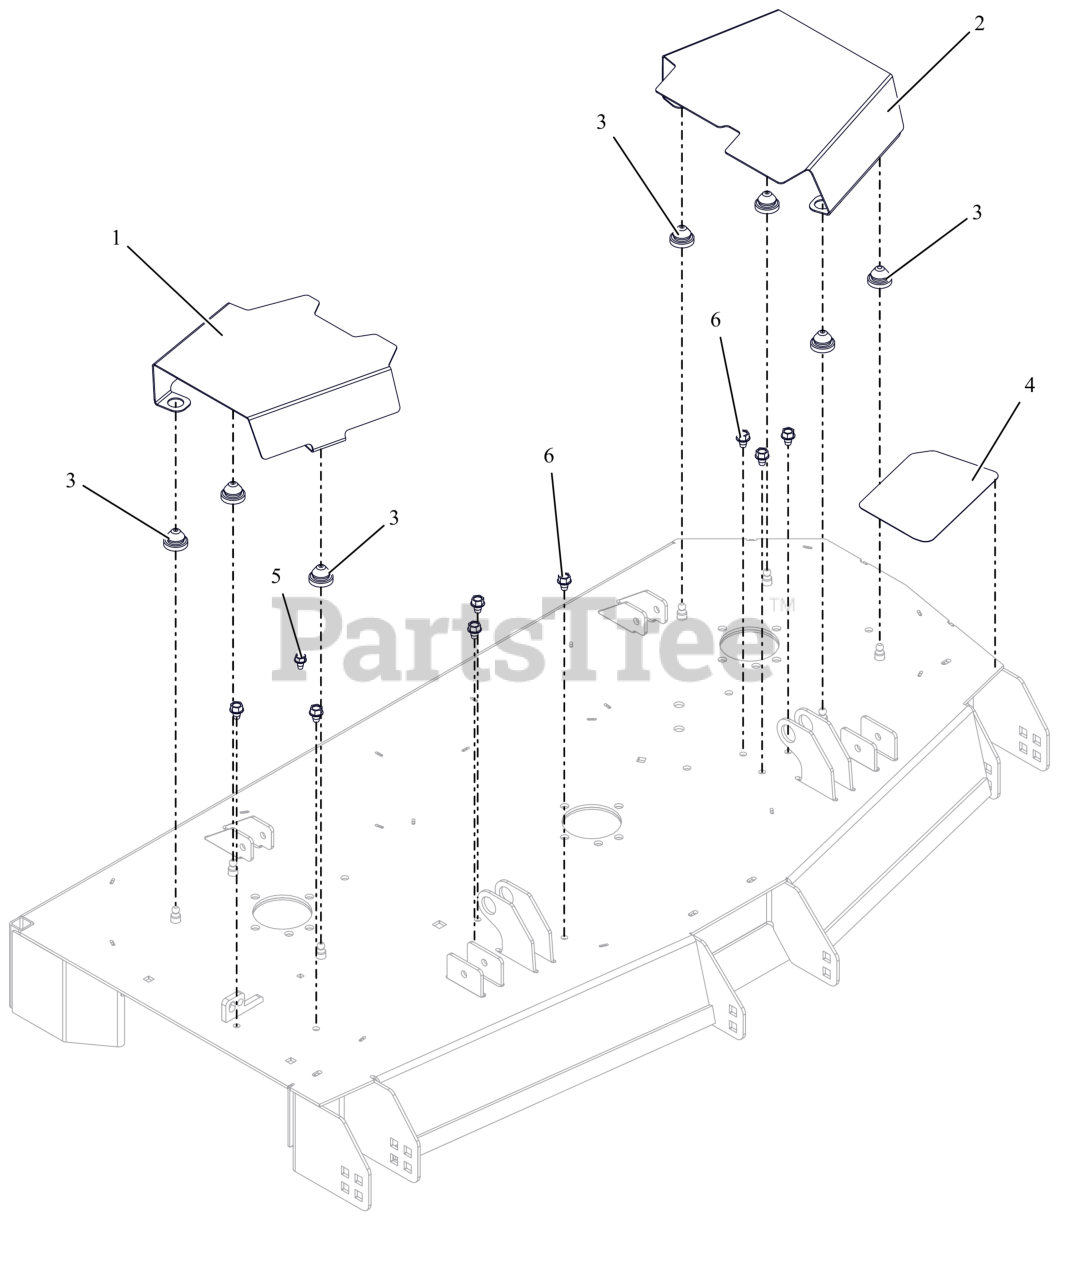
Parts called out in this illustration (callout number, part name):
1	COVER- BELT 52" RIGHT
2	COVER- BELT 52" LEFT
3	COUPLING, RUBBER PUSH-IN
4	GRIP, STEP ANTI SKID HD XF3
5	SCR,TAP .312-18X.50 HWH TR ZCC
6	SCR,TAP .375-16X.50 HWH TR ZCC
